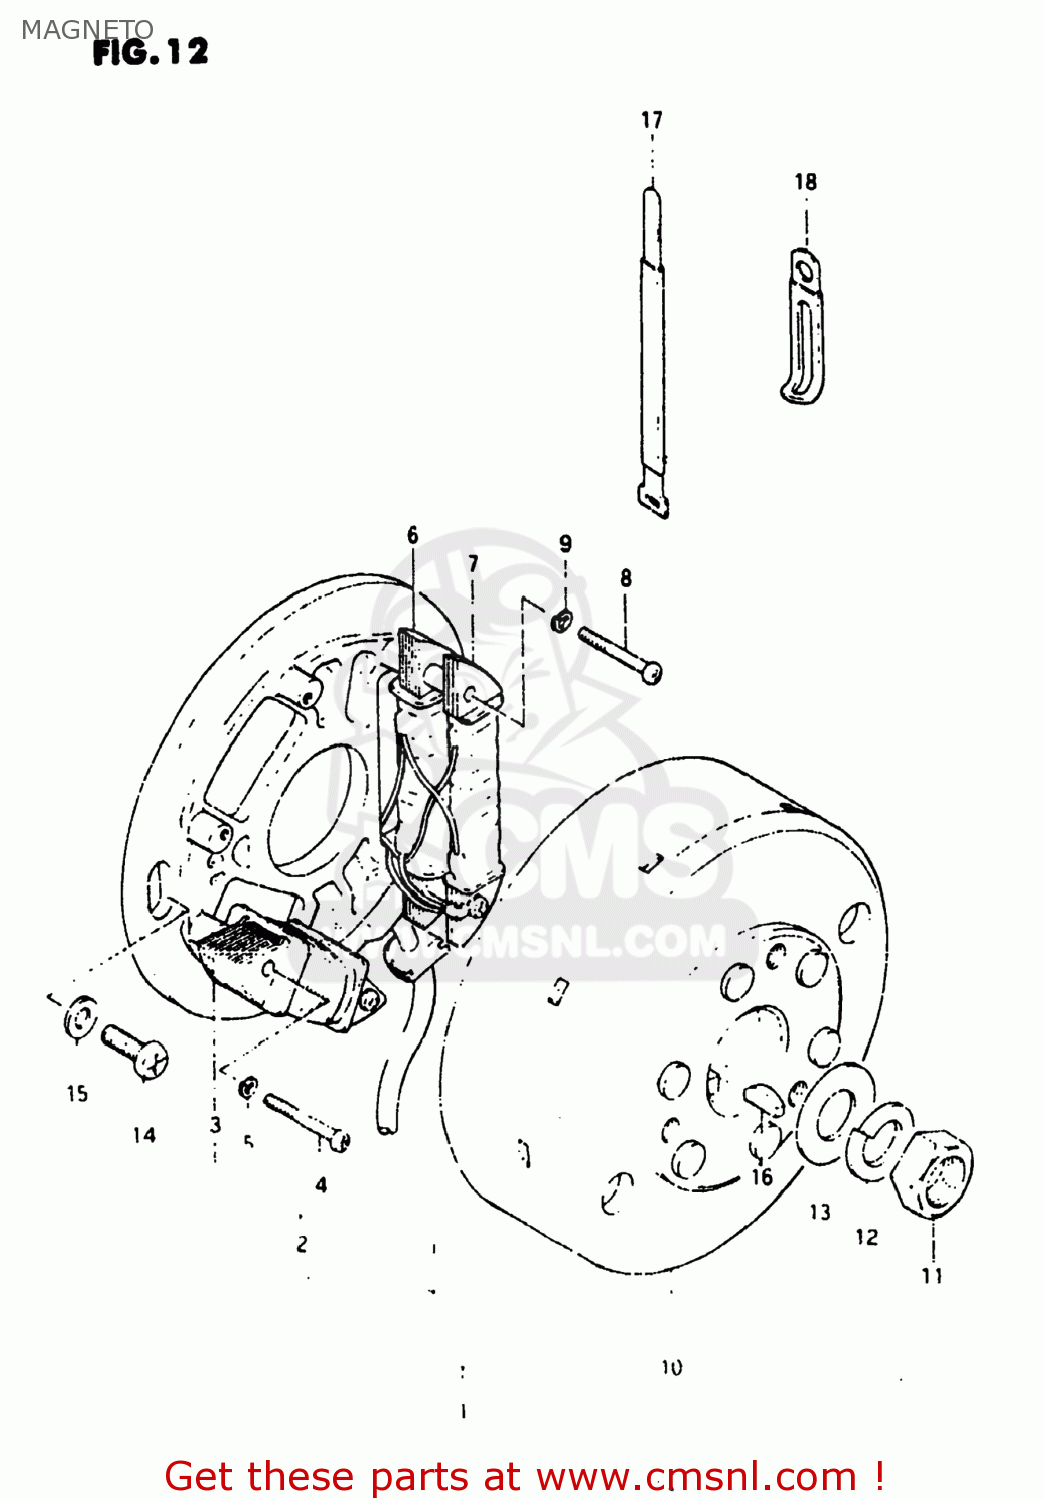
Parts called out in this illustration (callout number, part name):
1	MAGNETO ASSEMBLY
2	STATOR ASSEMBLY
3	COIL,LIGHTING
4	SCREW (4X30)
5	LOCK WASHER
6	COIL,PRIMARY
7	COIL,PULSER
8	SCREW
9	LOCK WASHER
10	ROTOR ASSEMBLY
11	NUT (10MM)
12	LOCK WASHER
13	WASHER
14	SCREW
15	WASHER
16	KEY 4MM
17	CLAMP L:110
18	CLAMP
